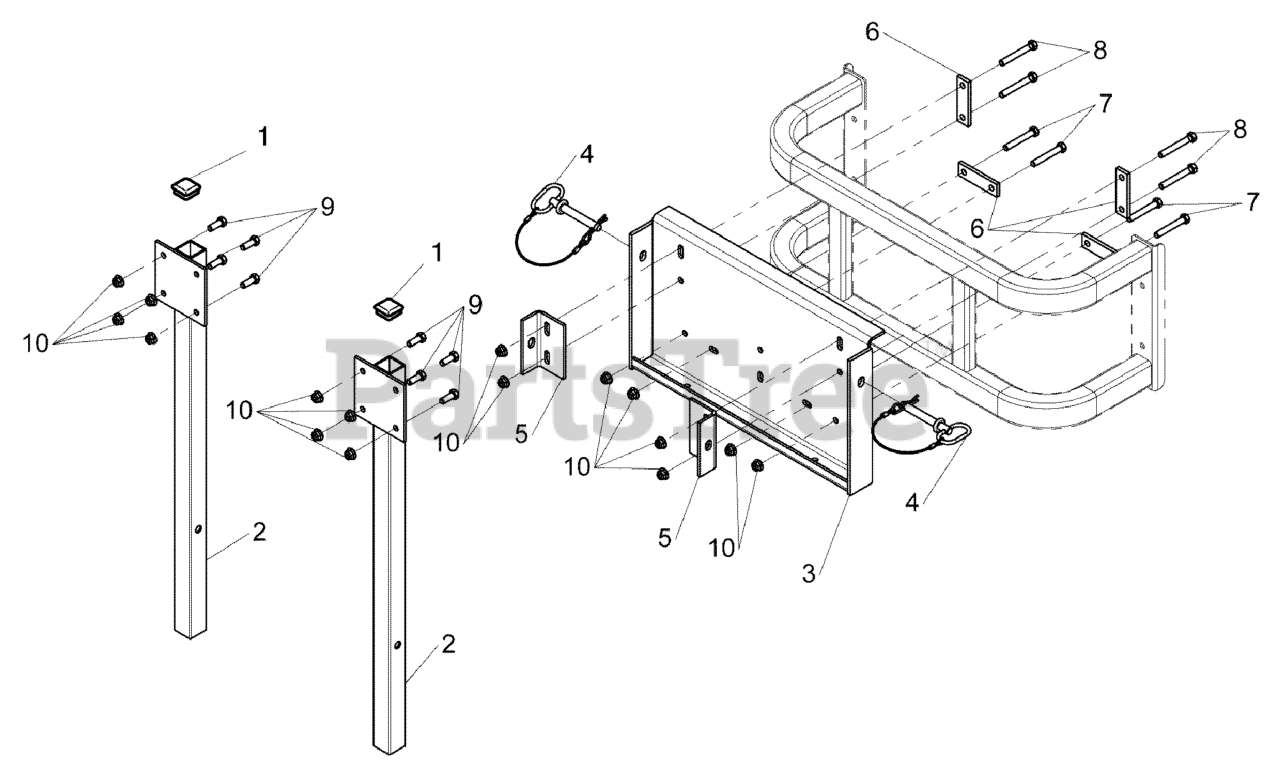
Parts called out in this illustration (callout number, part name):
1	CAP, PLASTIC, 1-1/2" X 1-1/2
2	WELD, MOUNT, POST - BLK
3	WELD, 3-BAG MOUNT, ALL - BLK
4	PIN, HITCH, .50 X 3.25 W/ LAY
5	MOUNT, TAB, BLACK
6	CLAMP, BAR
7	BOLT, 3/8-16 X 2-1/2" GD5 CZ
8	BOLT, 3/8-16 X 2-3/4" GD5 CZ
9	BOLT, 3/8-16 X 1" GD5 CZ
10	NUT, 3/8-16 HEX NYLOCK FLANGE
